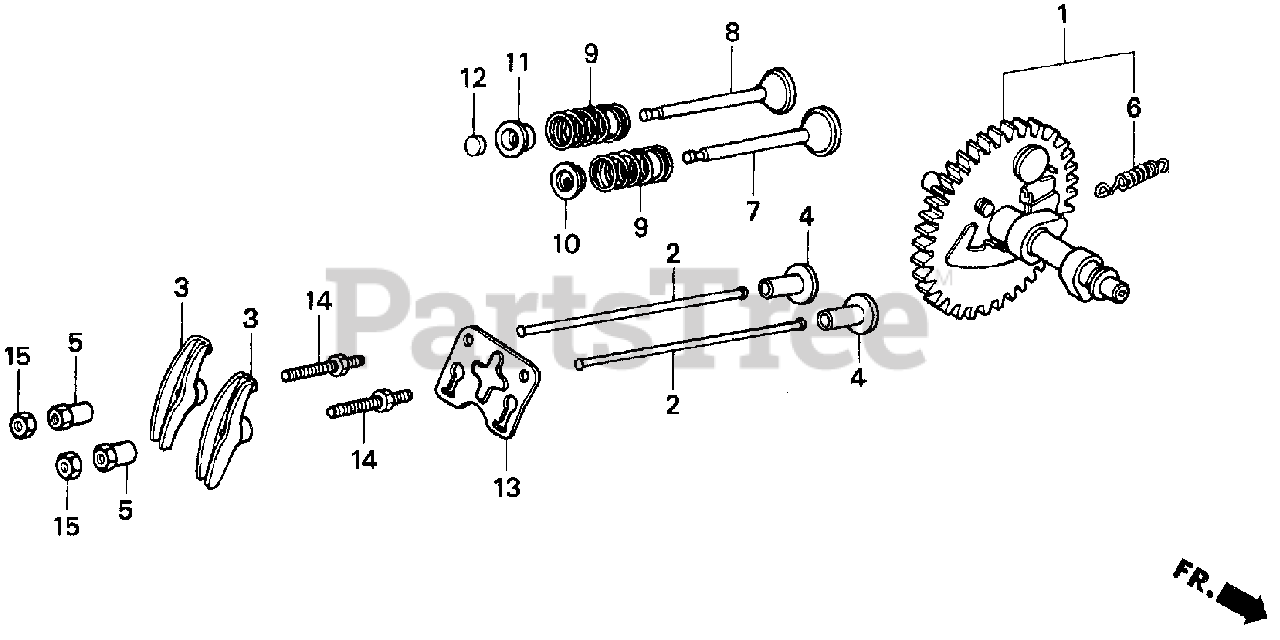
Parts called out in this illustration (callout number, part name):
1	CAMSHAFT ASSY.
2	ROD, PUSH
3	ARM, VALVE ROCKER
4	LIFTER, VALVE
5	PIVOT, ROCKER ARM
6	SPRING, WEIGHT RETURN
7	VALVE, IN.
8	VALVE, EX.
9	SPRING, VALVE
10	RETAINER, IN. VALVE SPRING
11	RETAINER, EX. VALVE SPRING
12	ROTATOR, VALVE
13	PLATE, PUSH ROD GUIDE
14	BOLT, PIVOT (8MM)
15	NUT, PIVOT ADJ.
